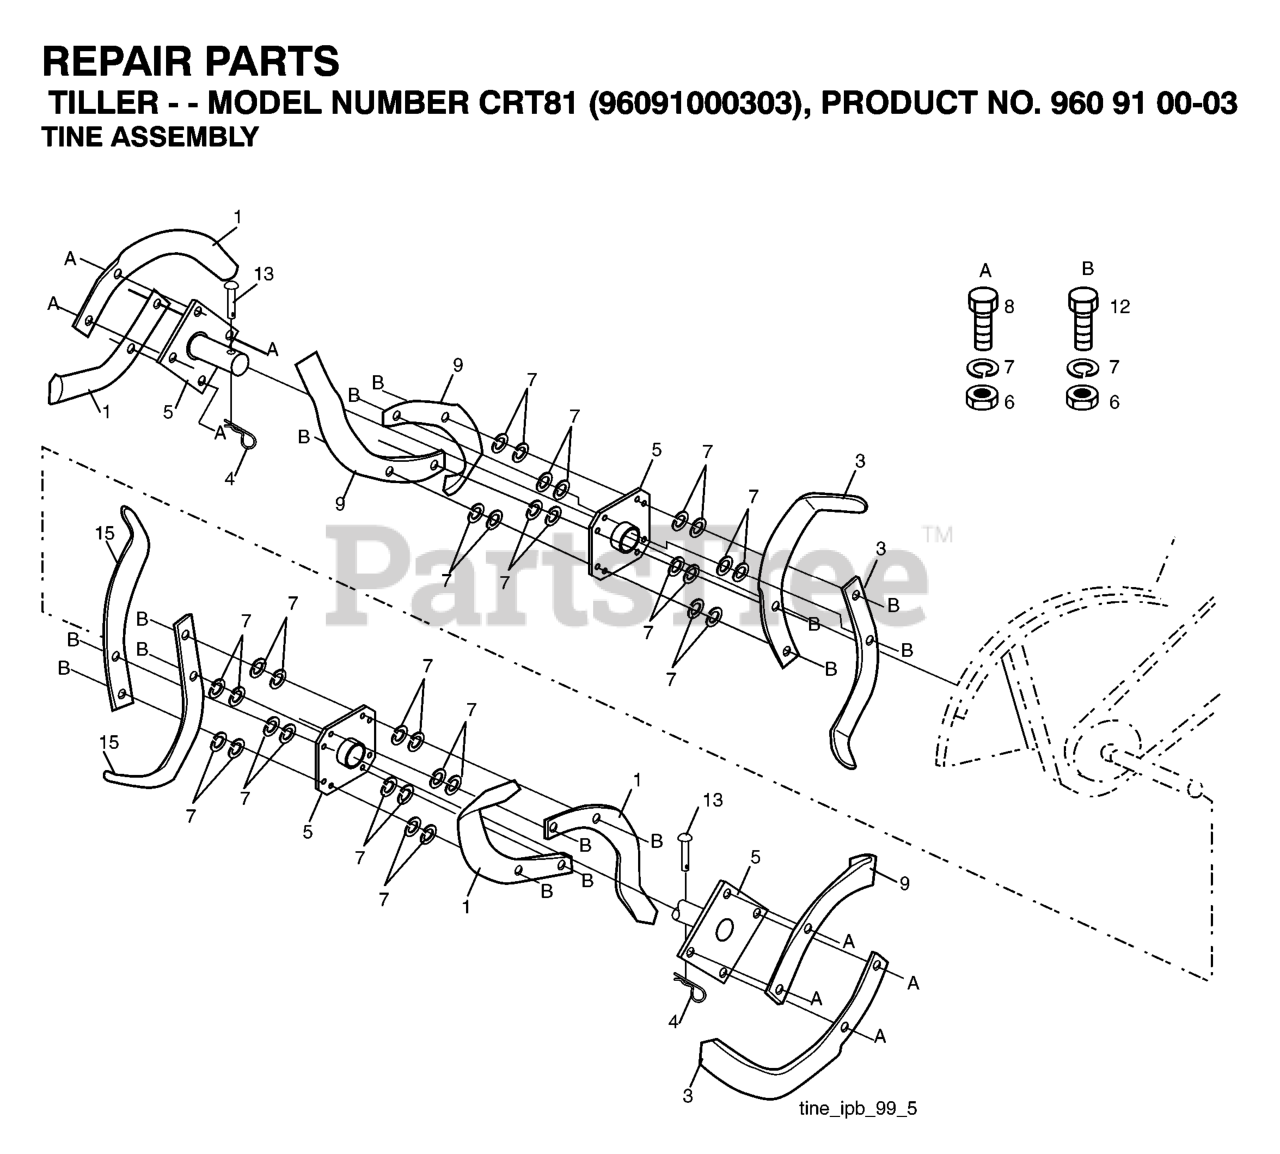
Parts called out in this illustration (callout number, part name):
1	TINE, LH 14"
3	TINE.LH.14".CRT
4	SPRING RETAINER
5	TINE.HUB.ASM.W/SHEILD
6	NUT
7	WASHER, LOCK 3/8
8	BOLT.HEX.001X20.37-24X1.ZINC
9	TINE, RH 14"
12	BOLT.3/8-24X1-1/2
15	TINE.RH.14".CRT
